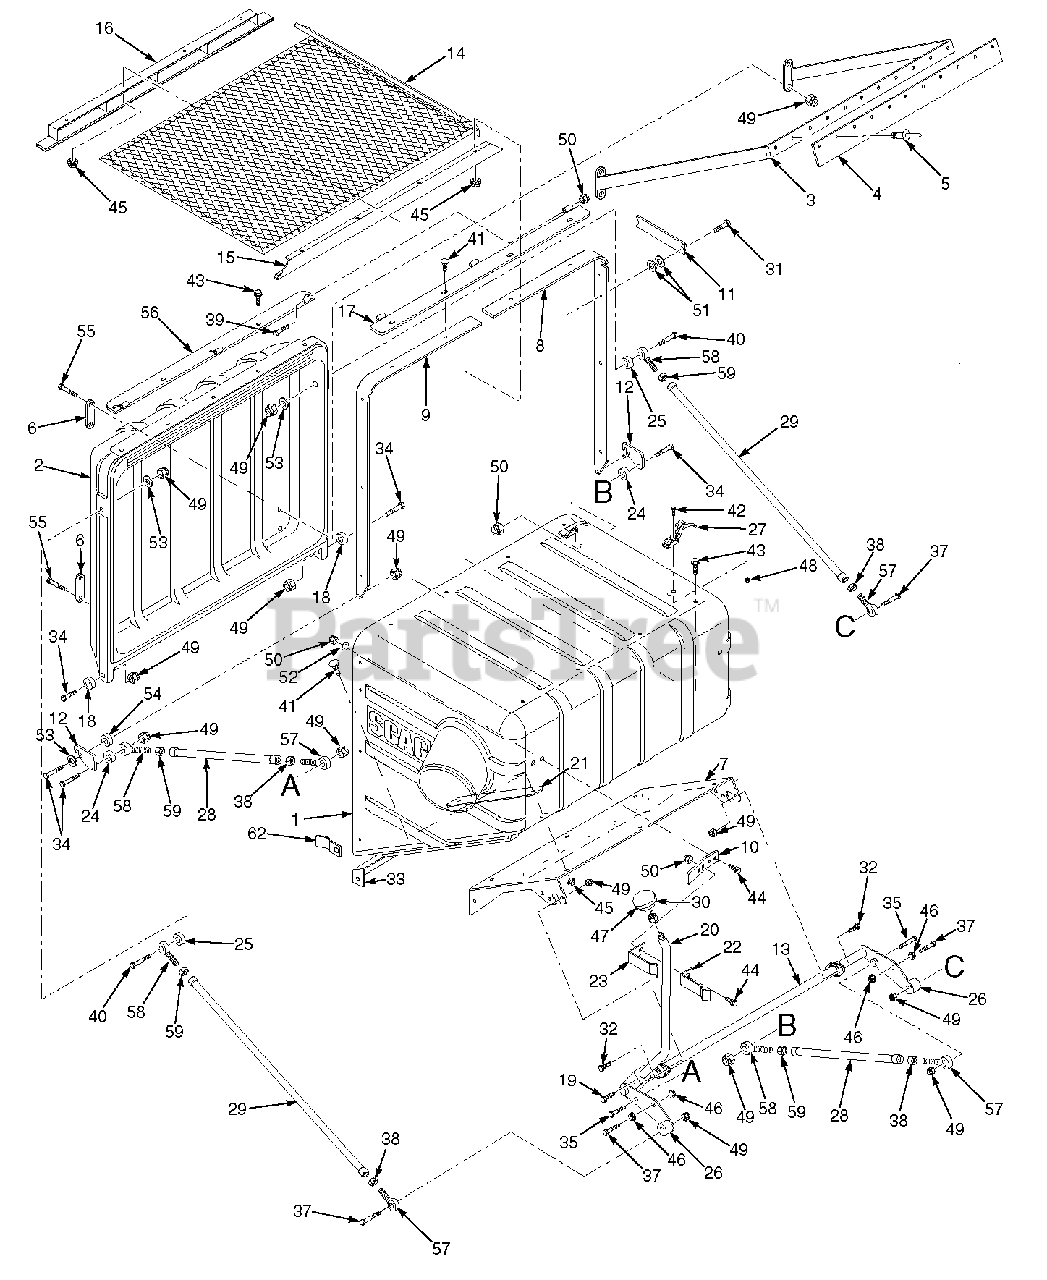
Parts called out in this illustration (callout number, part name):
1	Hopper, GC-STT-CS
2	Door, GC-CS
3	Sweeper Weldment, GC-CS
4	Pad, Rubber
5	Pop Rivet, 3/16 x .652
6	Plate, Stiffener
7	Support Frame, Hopper
8	Hinge Bracket, LH
9	Hinge Bracket, RH
10	Mounting Bracket, Dump Handle Latch
11	Latch, Door Prop
12	Plate, Latch
13	Bellcrank Weldment, Upper
14	Debris Screen Weldment
15	Screen Support Weldment, Rear
16	Screen Support Weldment, Front
17	Hinge Weldment, Hopper
18	Spacer
19	Bolt, Hex Head 5/16-18 x 1-3/4"
20	Rod, Dump Lever GC-SCZ-CS
21	Retainer Strip, Hopper
22	Latch, Dump Rod Inner
23	Latch, Dump Rod Outer
24	Spacer
25	Spacer
26	Spacer
27	Latch, Hood
28	Linkage Assembly, Lower
29	Linkage Assembly, Upper
31	Bolt, Hex Head 5/16-18 x 1-1/4"
32	Bolt, Hex Head 3/8-16 x 3/4"
33	Bracket, Lower Stiffener
34	Bolt, Hex Head 3/8-16 x 1-1/2"
35	Bolt, Hex Head 3/8-16 x 1-3/4"
36	Alignment Bracket, GC-CS
37	Bolt, Hex Head 3/8-16 x 2"
38	Nut, 3/8-24 UNF RH Thread
39	Bolt, Hex Head 5/16-18 x 3-1/2"
40	Bolt, Hex Head 3/8-16 x 3-1/2"
41	Bolt, Carriage 5/16-18 x 1"
42	Screw, #10-32 x 1/2"
43	Cap Screw, 5/16-18 x 3/4" Serr. Flan.
44	Cap Screw, 5/16-18 x 1" Serr. Flan.
45	Nut, 5/16-18 Serrated Flange
46	Nut, 3/8-16 Serrated Flange
47	Nut, 3/8-16 UNC Jam
48	Nut, #10-32 Elastic Stop
49	Nut, 3/8-16 Elastic Stop
50	Nut, 5/16-18 Elastic Stop
51	Washer, Special Wave
52	Washer, 5/16-.375 x .875 x .083 Flat
53	Washer, 3/8-.931 x .938 x .105 Flat
54	Bushing, Hopper Latch GC-CS
55	Bolt, Hex Head 3/8-16 x 3"
56	Hinge Weldment, Door
57	Rod End Male, 3/8-24 RH Thread
58	Rod End Male, 3/8-24 LH Thread
59	Nut, 3/8-24 UNF LH Thread
